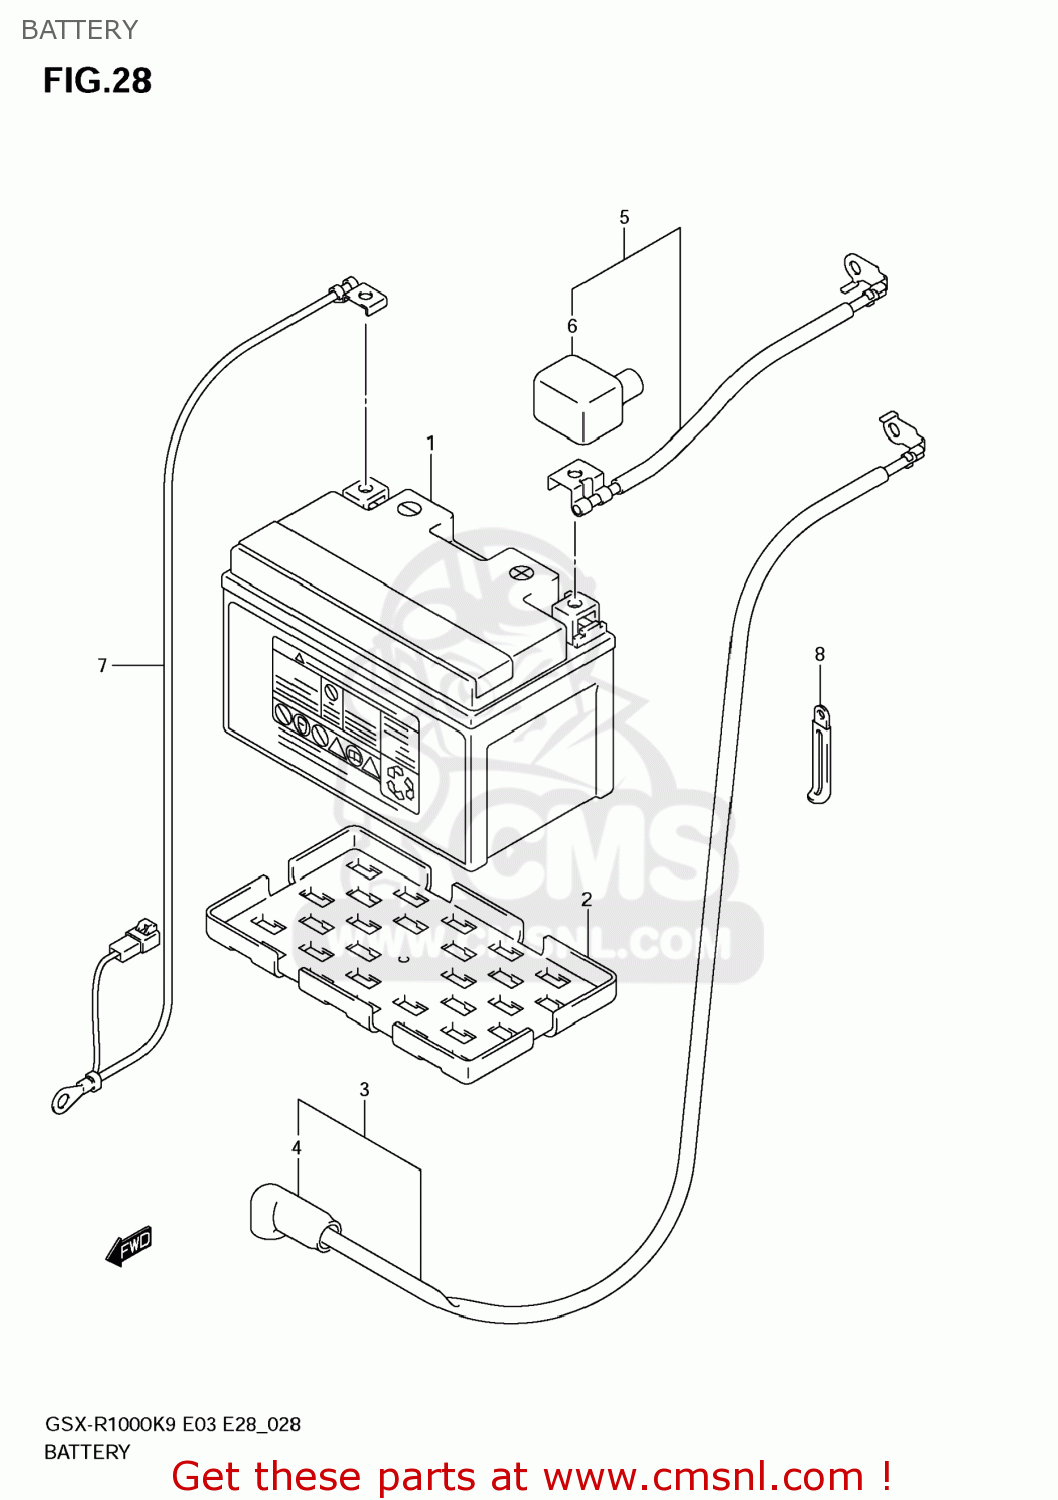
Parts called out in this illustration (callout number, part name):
1	BATTERY ASSY,F
2	PROTECTOR,BATTERY
3	WIRE,STARTER MOTOR LEAD
4	CAP,OIL PRESSURE SWITCH
5	WIRE,BATTERY PLUS LEAD
6	CAP,BATTERY PLUS
7	ACCUKABEL. NEG
8	CLAMP(L:45)
